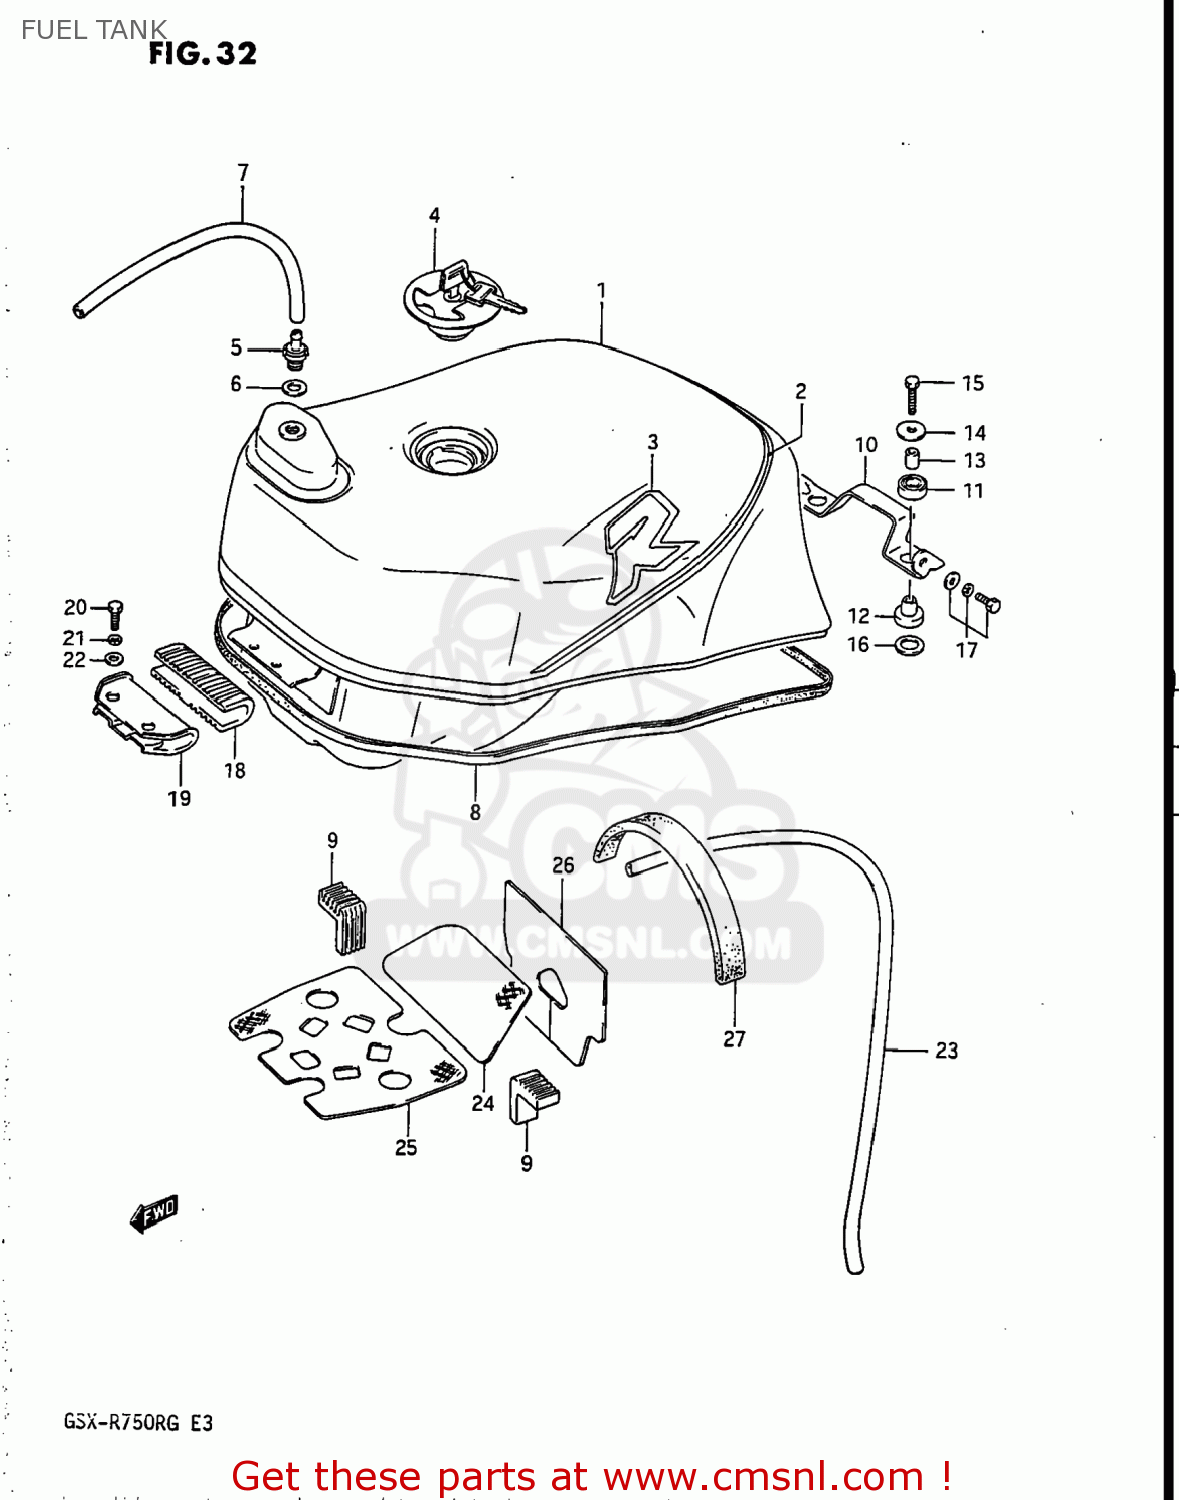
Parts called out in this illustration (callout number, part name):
1	TANK ASSEMBLY,FUEL
2	TAPE SET,FUEL TANK
3	EMBLEM
4	CAP SET,FUEL TANK
5	PLUG, FUEL TANK BREATHER
6	GASKET 27X40X2.5 (NAS)
7	HOSE,FUEL
8	MOLDING,FUEL TANK
9	CUSHION,FUEL TANK SIDE
10	BRACKET,SEAT SUPPORT,FRONT
11	CUSHION
12	CUSHION
13	SPACER
14	WASHER (6.5X24X1.6)
15	BOLT ,6X35
16	WASHER (12.5X24X1.6)
17	SCREW(6X16)
18	CUSHION,FUEL TANK FR
19	BRACKET,FUEL TANK FR
20	BOLT
21	WASHER,LOCK
22	WASHER
23	HOSE,FUEL
24	SHIELD,FUEL TANK HEAT
25	SHIELD,FUEL TANK HEAT
26	SHIELD,HEAT NO.1
27	SHIELD,TANK & CLEANER
